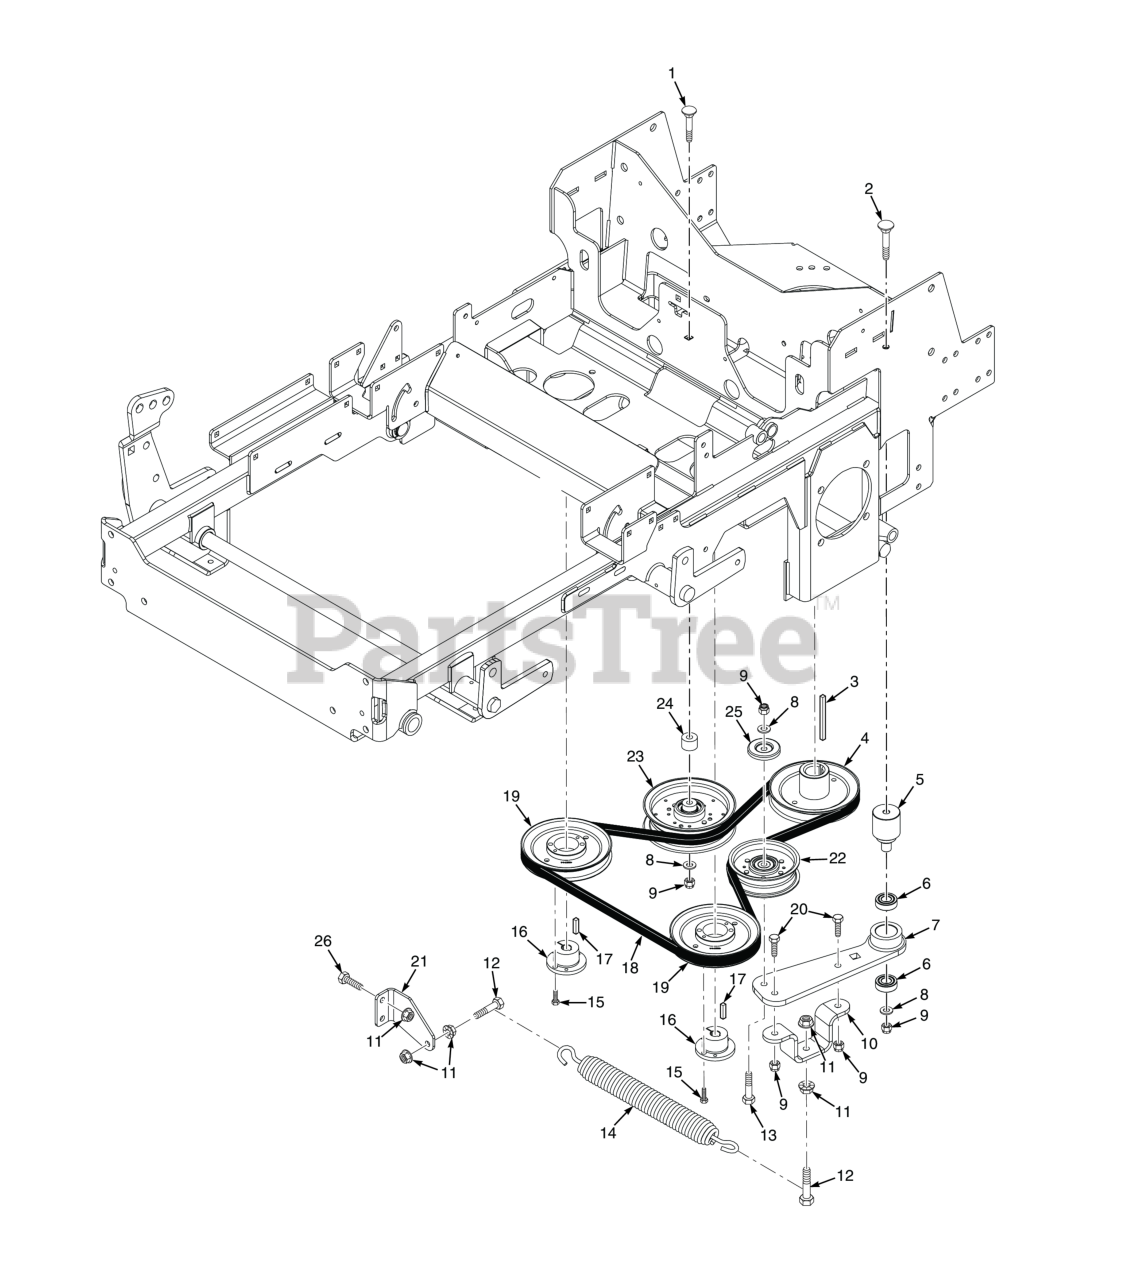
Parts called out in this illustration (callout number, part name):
1	Bolt, Carriage 3/8-16 x 3-1/4"
2	Bolt, Hex Head 3/8-16 x 3-1/2"
3	Key, 1/4 x 1/4 x 3-1/2"
4	Pulley, 5.75" Dia. - 1.125 Bore
5	Pivot, Idler Arm
6	BEARINGS, BALL, NEUTRAL RETURN
7	Idler Arm Assembly
8	Flatwasher, 3/8 (.391 x .938 x .105 HD) Grade 8
9	HEX NUT, ELASTIC STOP LOCK, 3/8-16
10	Mounting Bracket, Idler
11	NUT, 3/8-16 SERRATED FLANGE HEX HEAD
12	Bolt, Hex Head 3/8-16 x 1-1/2" Grade 8 Black
13	Bolt, Hex Head 3/8-16 x 2-1/4" - 61"
14	Spring, Pump Drive
15	Bolt, Hex Head 1/4-20 x 1" Grade 8 Black
16	Hub, Tapered, 15mm Bore
17	KEY, 5 MM X 5 MM X 25 MM
18	Belt, Pump Drive (61")
19	Pulley, 5.75 O.D. (Gasoline Engines)
20	Bolt, Hex Head 3/8-16 x 1-1/4", Kawasaki FX / FT & FT-EFI
21	Bracket, Spring Anchor
22	Pulley, 4" Dia. Idler
23	Idler Pulley, Belt Clutch
24	Spacer, Idler
25	Quick Pin, 5/16" Dia.
26	Carriage Bolt, 3/8-16 x 1.0"
